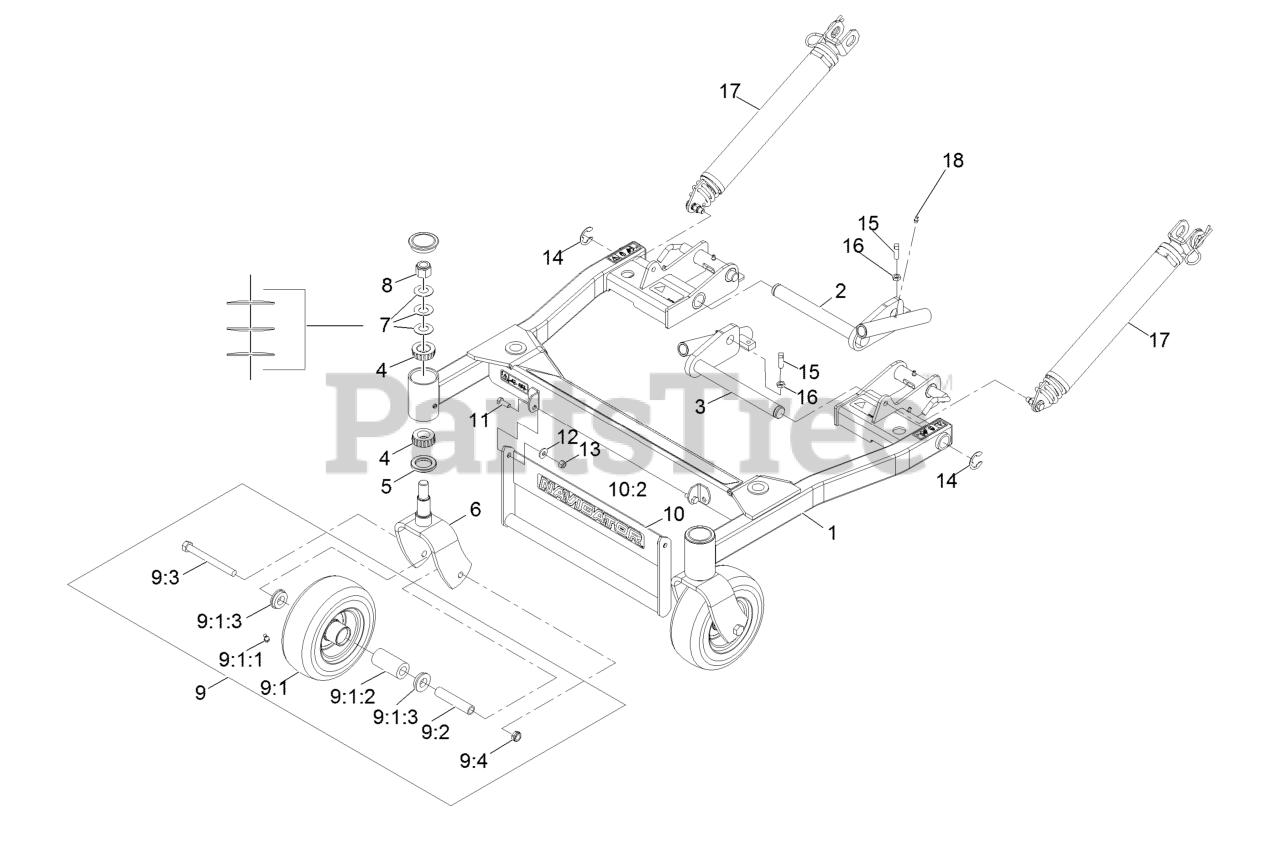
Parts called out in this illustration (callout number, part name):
1	Deck Support ASM
2	Pivot-Deck, RH
3	Pivot-Deck, LH
4	Cone-Bearing Tapered Roller
5	Seal-Grease
6	Fork-Caster
7	Washer-Spring Disc
8	Nut-Nyloc 3/4-10
9	Asm, Caster Wheel W/Axle
9:1	Asm, Wheel And Tire 8X3.00-4 Sp
9:1:1	Zerk-45deg 1/4-28
9:1:2	Bearing-Roller, Straight
9:1:3	Bushing-Flanged
9:2	Spacer-Caster, Front
9:3	Screw-HH 1/2-13 X 5
9:4	Nut-Nyloc 1/2-13 Thin
10	Asm, Deck Lift Handle W/Decal
10:2	Decal-Navigator Logo
11	Screw-HH 5/16-18 X 7/8
12	Washer-Spring Disc 5/16
13	Nut-Nyloc 5/16-18
14	Ring-Snap
15	Setscrew-SQH 3/8-16 X 1
16	Nut-Jam 3/8-16
17	Lift Assist Spring ASM
18	Zerk-1/4-28 Str
